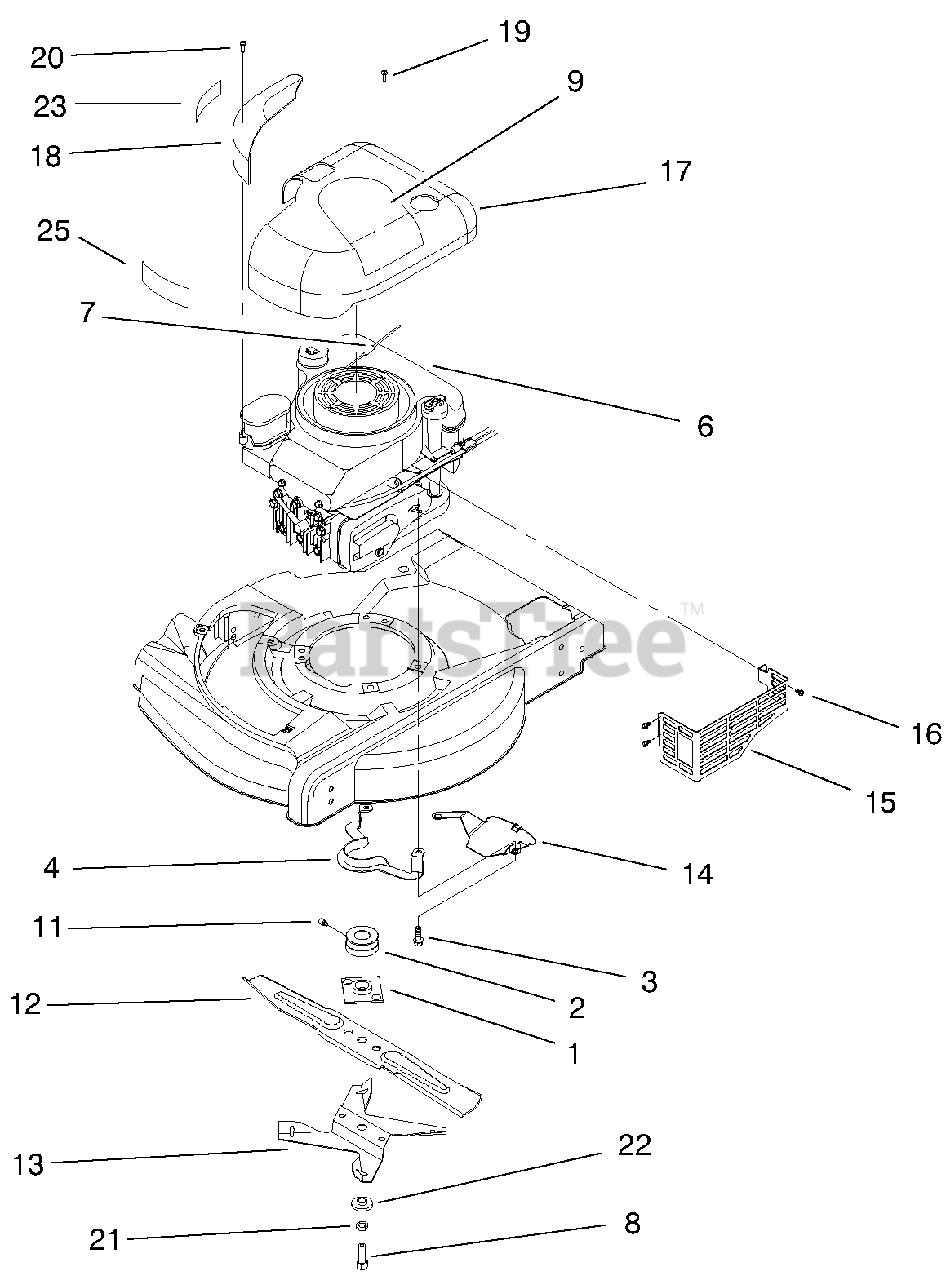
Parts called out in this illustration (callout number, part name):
1	ASM-Plate & Collar
2	Pulley-Engine
3	Screw-Engine Mount
4	Guide-Belt
6	ASM-Engine
7	Rope-Stop (P/W Eng)
8	Bolt-Blade
9	Decal-Recoil
11	Screw-Set
12	Blade-21" Whirl
13	Fan-Mulching
14	Shield-Grass
15	Shield-Muffler
16	Screw-HWHTF
17	Shroud-Engine (P/W Eng)
18	Cover-Air Cleaner (P/W)(Incl. Ref. #23)
19	Screw-Shroud (P/W Eng)
20	Screw-Air Cleaner (P/W)
21	Washer-Lock
22	Spacer-Blade
23	Decal-Primer
25	Applique
